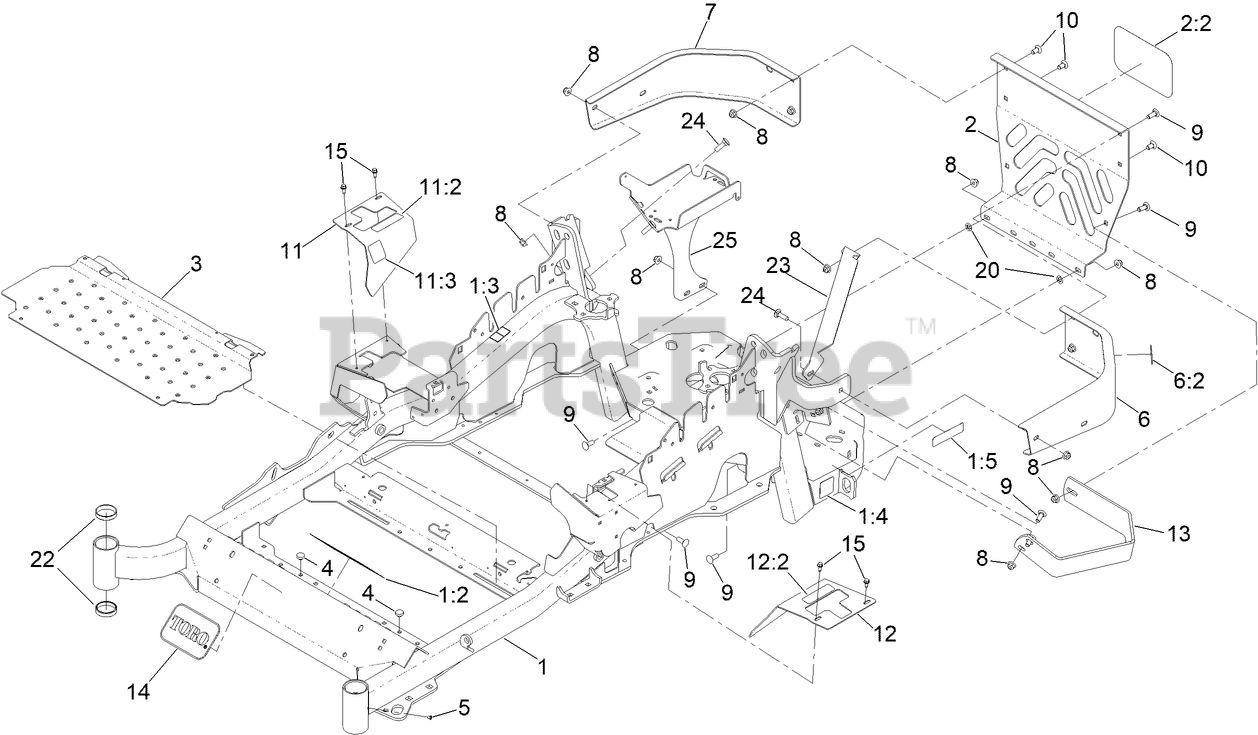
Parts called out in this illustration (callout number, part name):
1	MAINFRAME SERVICE ASM - 48/52
1:2	DECAL-DANGER
1:3	DECAL-WARNING
1:4	DECAL-HAZARD, PINCHED FINGER
1:5	DECAL-ARRESTOR, SPARK
2	REAR GUARD ASM
2:2	DECAL
3	FLOORPAN
4	BUMPER
6	LH BUMPER ASM
6:2	DECAL-WARNING
7	BUMPER-RH
8	NUT-HF, NI
9	SCREW-CARR
10	SCREW-CARR
11	RH MOTION CONTROL COVER ASM
11:2	DECAL-CONTROL, MOTION
11:3	DECAL-PARK BRAKE, CE
12	LH MOTION CONTROL COVER ASM
12:2	DECAL-CONTROL, MOTION
13	GUARD-MUFFLER
14	DECAL
15	SCREW-HWH
20	NUT-PUSH
22	CUP-BEARING
24	BOLT-CARR
25	BATTERY MOUNT ASM
